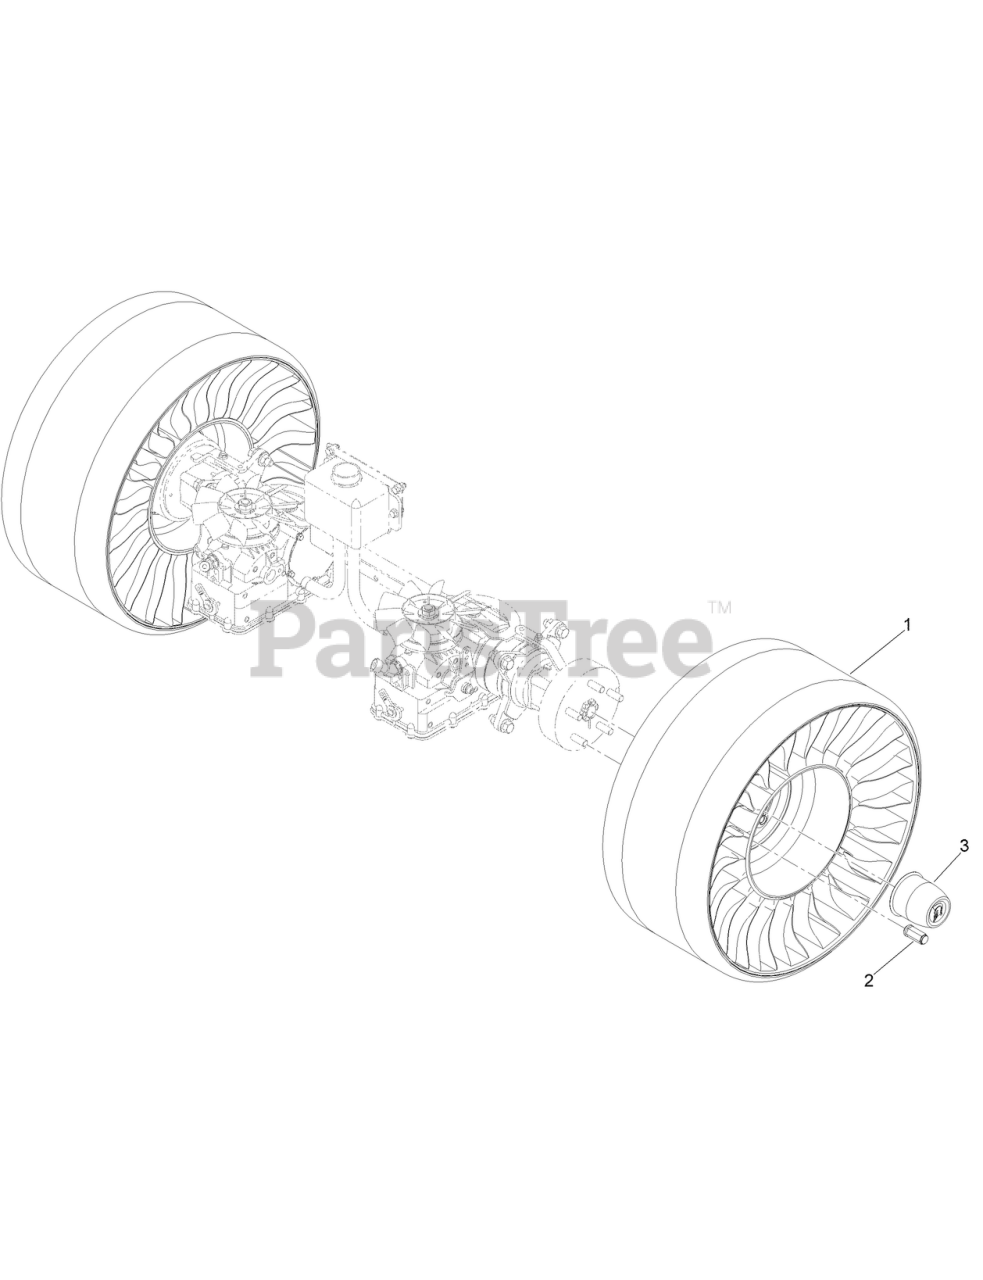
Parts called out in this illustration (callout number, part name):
1	TWEEL 24X12N12L 54411
2	LUG NUTS
3	RR STEEL WHEEL SILVER CNTR CAP
